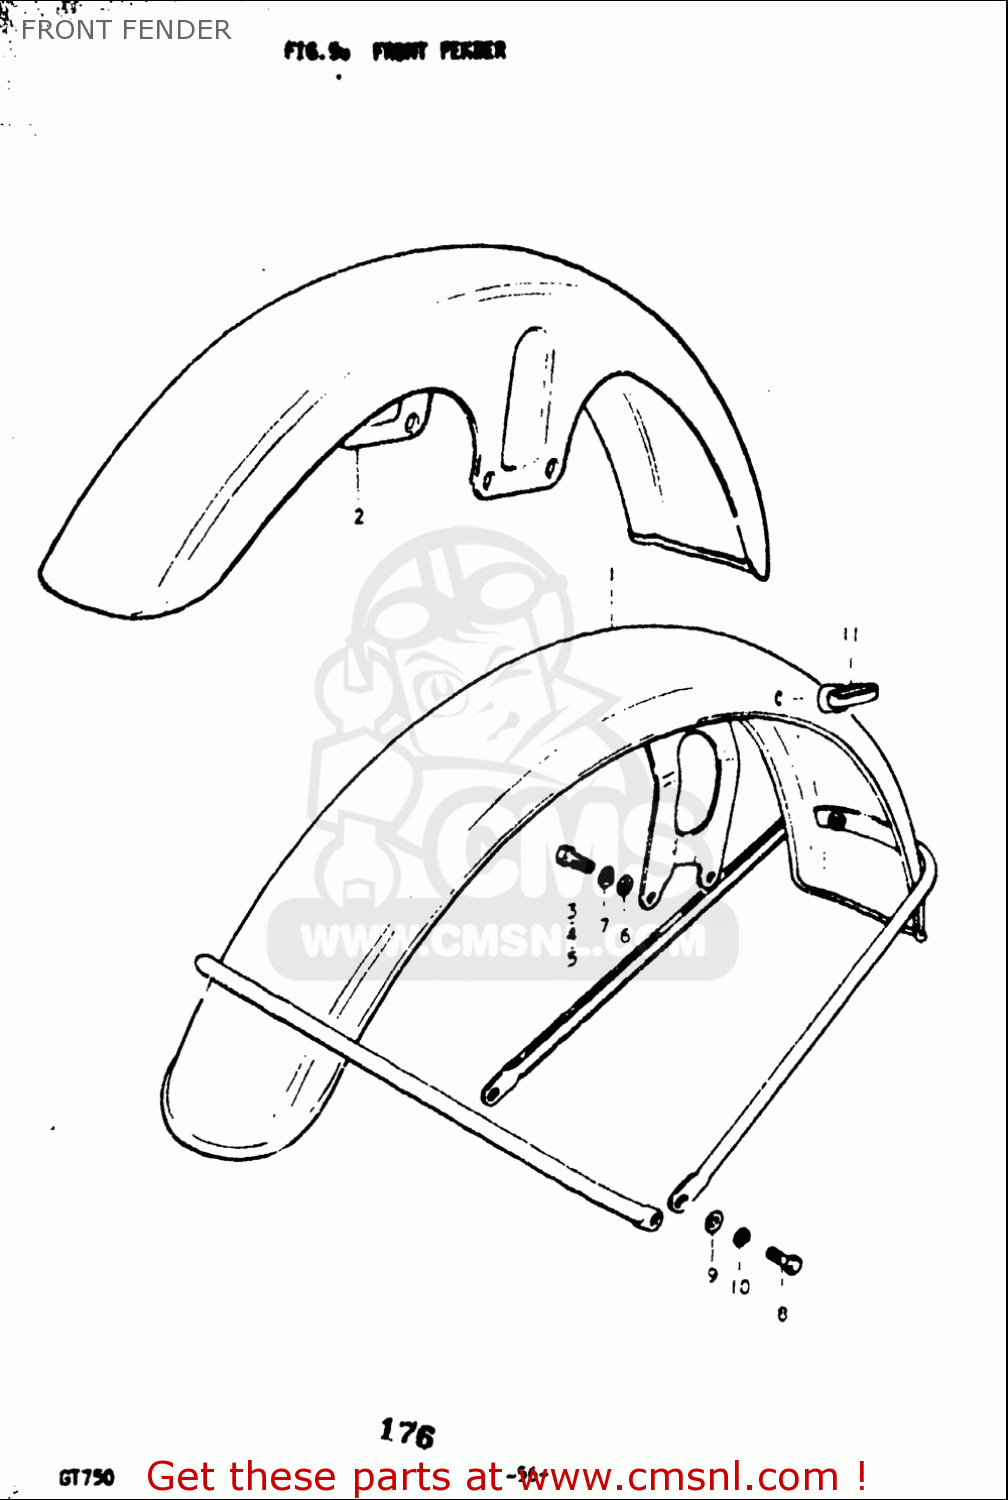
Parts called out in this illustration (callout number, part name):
1	FENDER ASSY,FR
3	BOLT
4	BOLT
5	BOLT
6	WASHER
7	WASHER,LOCK
8	BOLT
9	WASHER
10	WASHER,LOCK
11	GUIDE,CABLE
